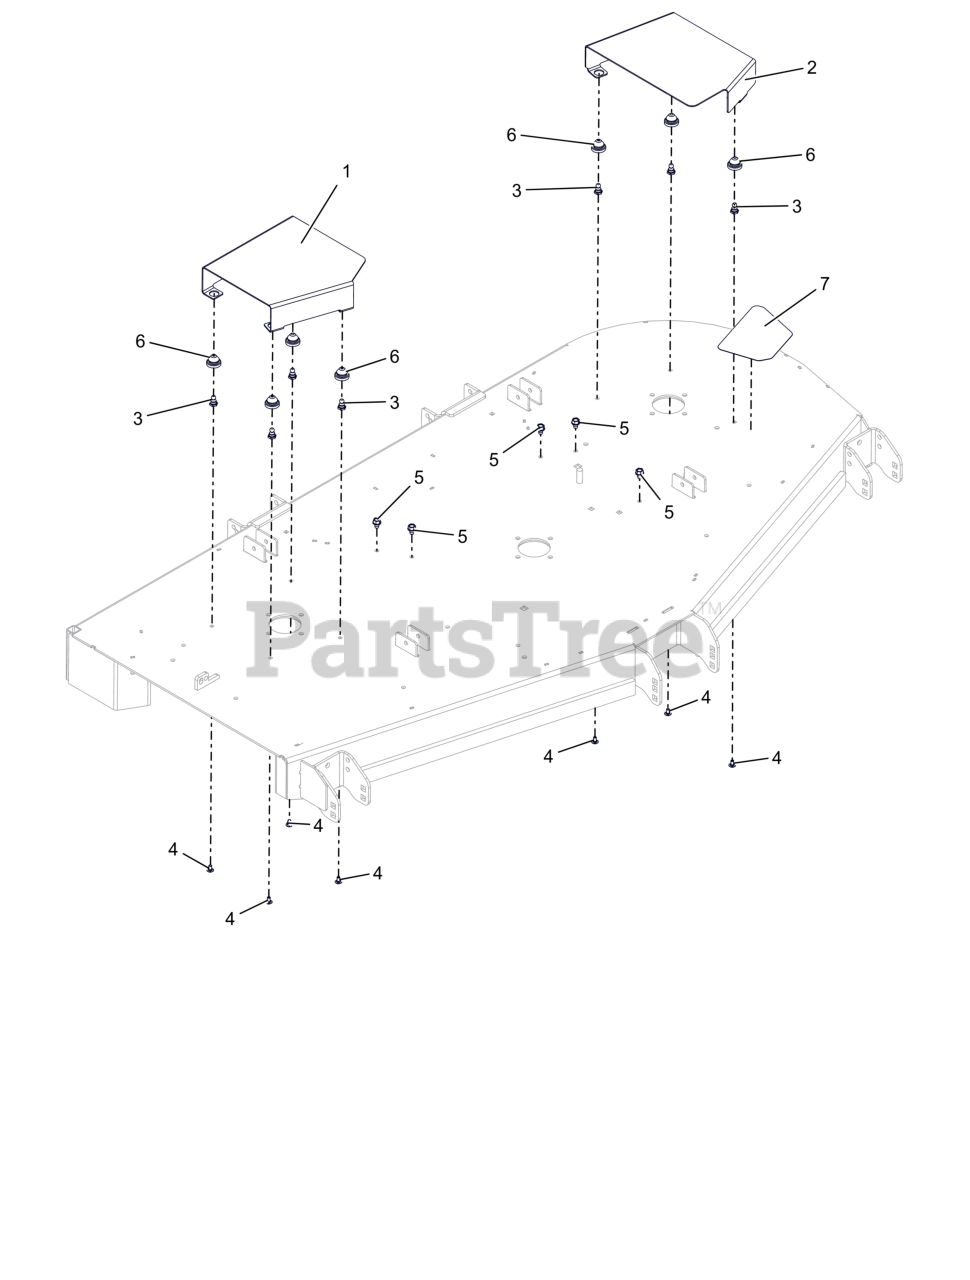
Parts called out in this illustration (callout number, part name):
1	GUARD, 72" DECK RH SPINDLE PULLEY
2	GUARD, 72" DECK LH SPINDLE PULLEY (RED)
3	STUD, BALL FEMALE .250-20 THREAD
4	BLT, RHSSN.25-20X.500 G5 ZCC
5	SCR,TAP .375-16X.50 HWH TR ZCC
6	COUPLING, RUBBER PUSH-IN
7	GRIP, STEP ANTI SKID
